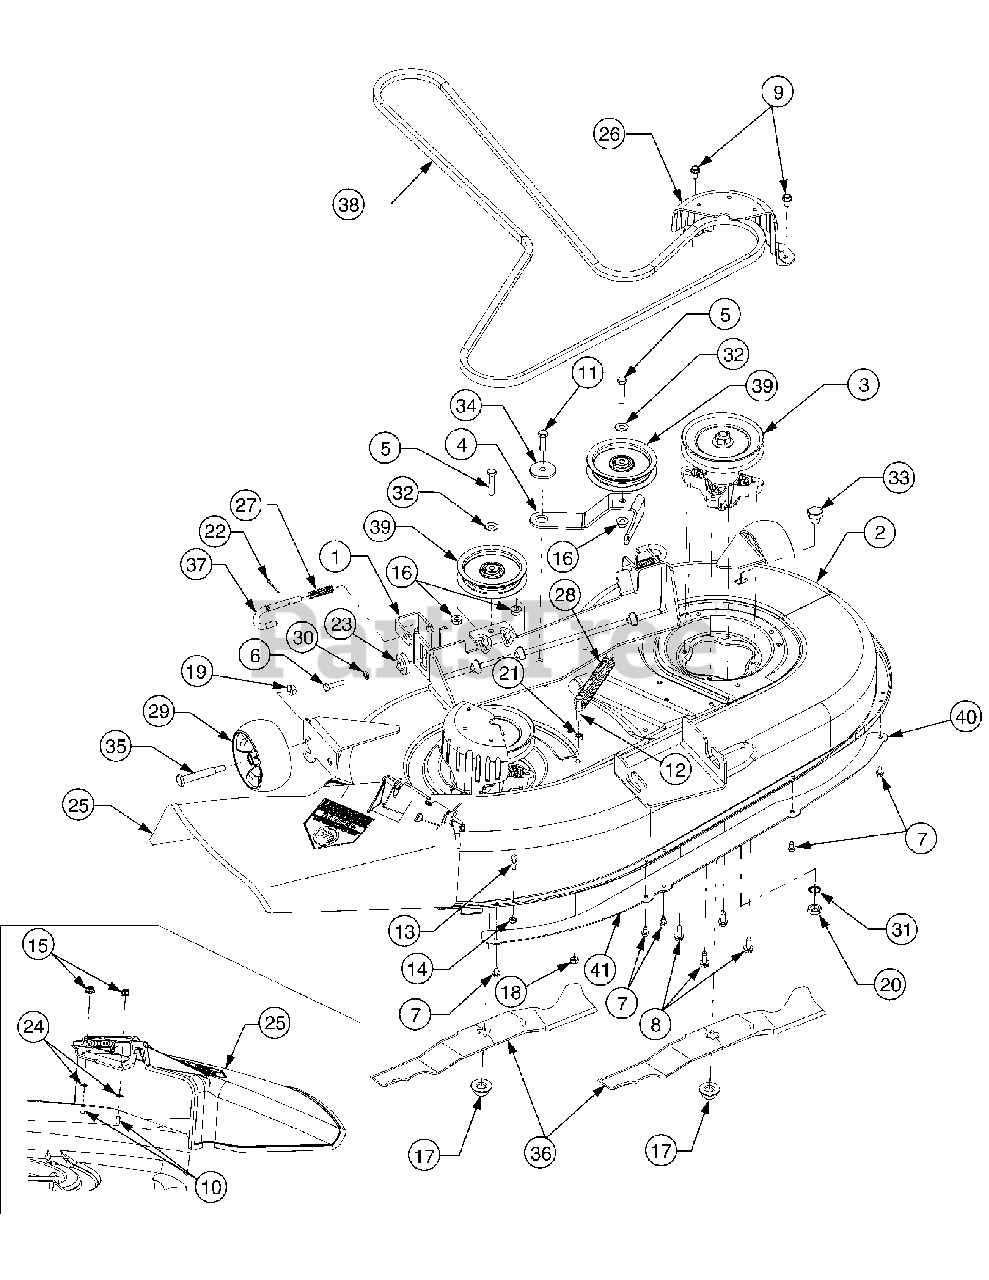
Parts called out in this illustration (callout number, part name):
2	Graphic, Danger
2	Graphic, Instruction
3	Spindle Assembly
3	Pulley
5	Screw, Hex Cap, 3/8-16 x 1.75 GR5
6	Screw, Hex Cap, 5/16-18 x 1.25 GR5
7	Screw, Hex Wash. Hd. Tapp 1/4-20 x .5
8	Screw, Hex Wash. Hd. Tapp 5/16-18 x .875
9	Screw, Hex Wash. Hd. Tapp 5/16-12 x .75
10	Screw, Hex Cap, 1/4-20 x .62 GR5
11	Screw, Hex Cap, 3/8-16 x 1.25 GR5
12	Screw, Hex Cap, 5/16-18 x 1.75 GR5
13	Pin, Grass Catcher, 1/4-20
14	Nut, Hex Insert Lock, 1/4-20 GR8
15	Nut, Hx Insert Flange Lck, 1/4-20 GR5
16	Nut, Hx Insert Flange Lck, 3/8-16 GrF
17	Nut, Hex Flange, 5/8-18
18	Nut, Hex Insert Lock, 5/16-18 GR5 ..
19	Nut, Hex Flange Lock, 3/8-16 GrF
20	Nut, Hex, M16-1.5
21	Nut, Hex, 5/16-18 GR5
22	Pin, Cotter, 1/8 x 1.25
23	Gear, Deck Adjustment
24	Nut, Push, .25 x .5
25	Chute Assembly, Discharge
25	Graphic, Danger
26	Cover, Belt
27	Spring, Compression
28	Spring, Extension, .94 Dia. x 6.74
29	Wheel, Deck Ball, 5.0
30	Washer, Lock, 5/16
31	Washer, Lock,
32	Washer, Flat, .38 x .93 x .11 HT
33	Plug, Screw, M16 x 1.5
34	Spacer, Shoulder, .884 x .19
35	Screw, Shoulder, .5 x 2.5:3/8-16
36	Blade, 3 in 1, 21.23
37	Rod, Deck Hanger
38	Belt, V, Type A Sec x 109
39	Pulley, Idler, 4.25 Dia.
